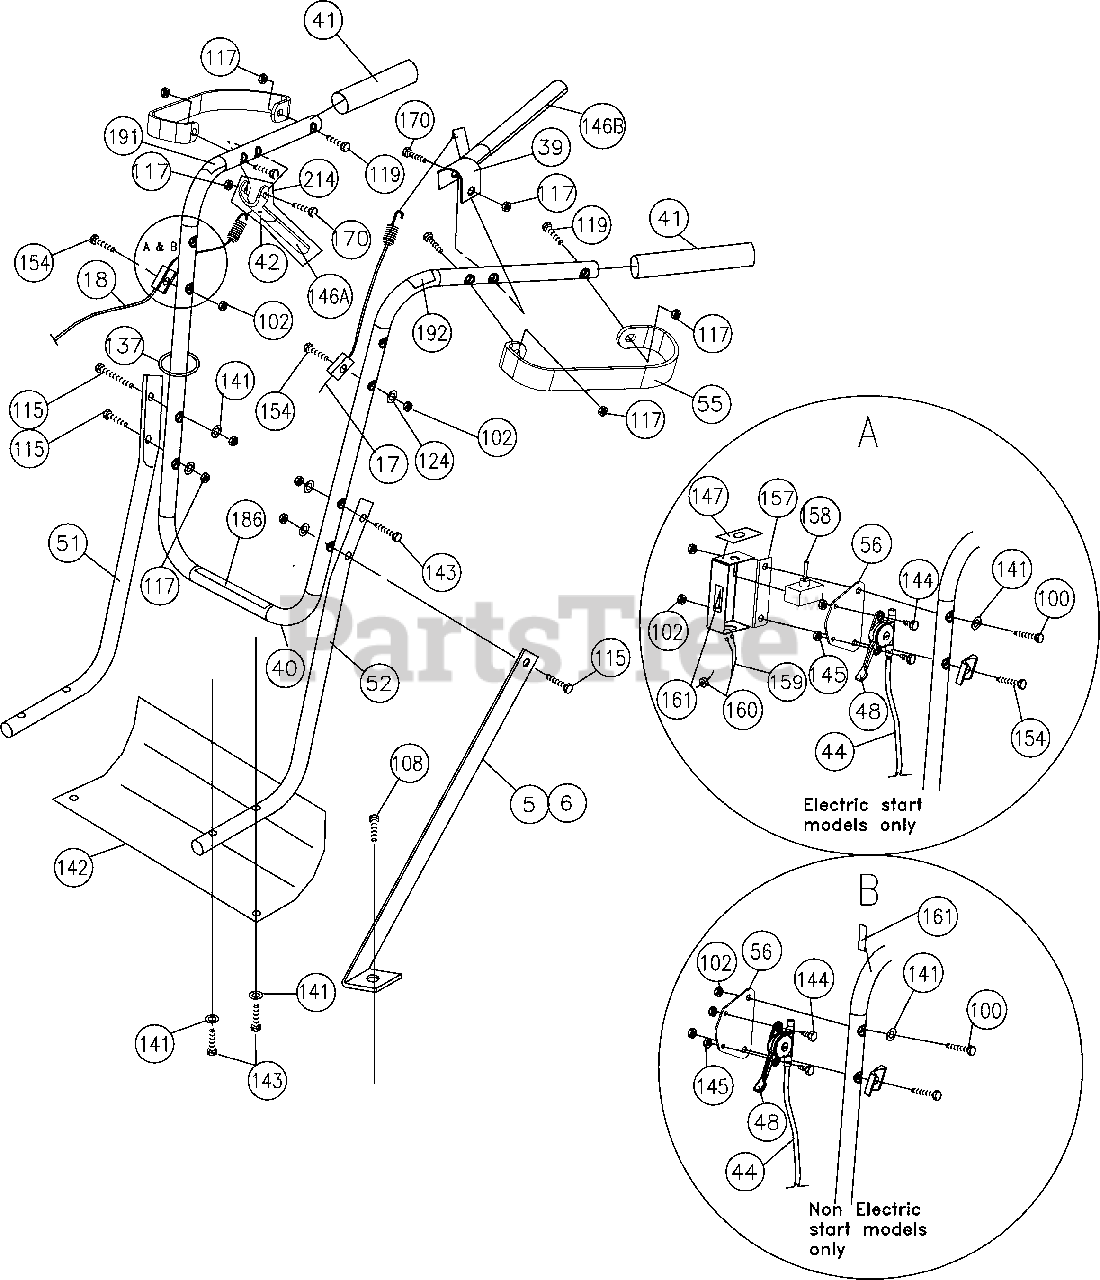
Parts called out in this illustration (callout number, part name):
5	Handle Brace Left
6	Handle Brace Right
17	Cable Clutch Blade BC2402
18	Cable Clutch Drive BC2402
39	Lever Control Blade
40	Handle Upper BC2403
41	Grip Handle 1” ID x 7.5”
42	Lever Control Clutch
44	Cable Throttle Control 36.0”
48	Control Throttle
51	Handle Lower RH BC2402
52	Handle Lower LH BC2402
55	Guard Hand BC2402
56	Throttle Plate BC2403
100	Screw cap ¼-20 x 1 1/4
102	Nut Lock 1/4-20
108	Screw Cap 5/16-18 x 2-3/4”
115	Screw Cap 5/16-18 x 2"
117	Nut Lock 5/16-18
119	Screw Cap 5/16-18 x 1-1/2”
124	Washer 1/4” FC
141	Washer 5/16” FC
142	Bracket Clutch Cable Guard
143	Screw Cap 5/16-18 x 1-3/4”
144	Screw Mach Flat HD Phil #10-24
145	Nut Lock LT #10-24
146A	Grip Lever Yellow
146B	Grip Lever Orange
147	Label Start/Stop Toggle
154	Screw Cap 1/4-20 x 1 3/4”
157	Switch box BC2403
158	Switch Toggle, ON/OFF
159	Harness Assy
160	Bushing Strain Relief
161	Label Throttle
170	Bolt Shoulder 3/8-16 x 1-1/2”
186	Label Shift BC2402
191	Label Clutch Drive
192	Label Clutch Blade
